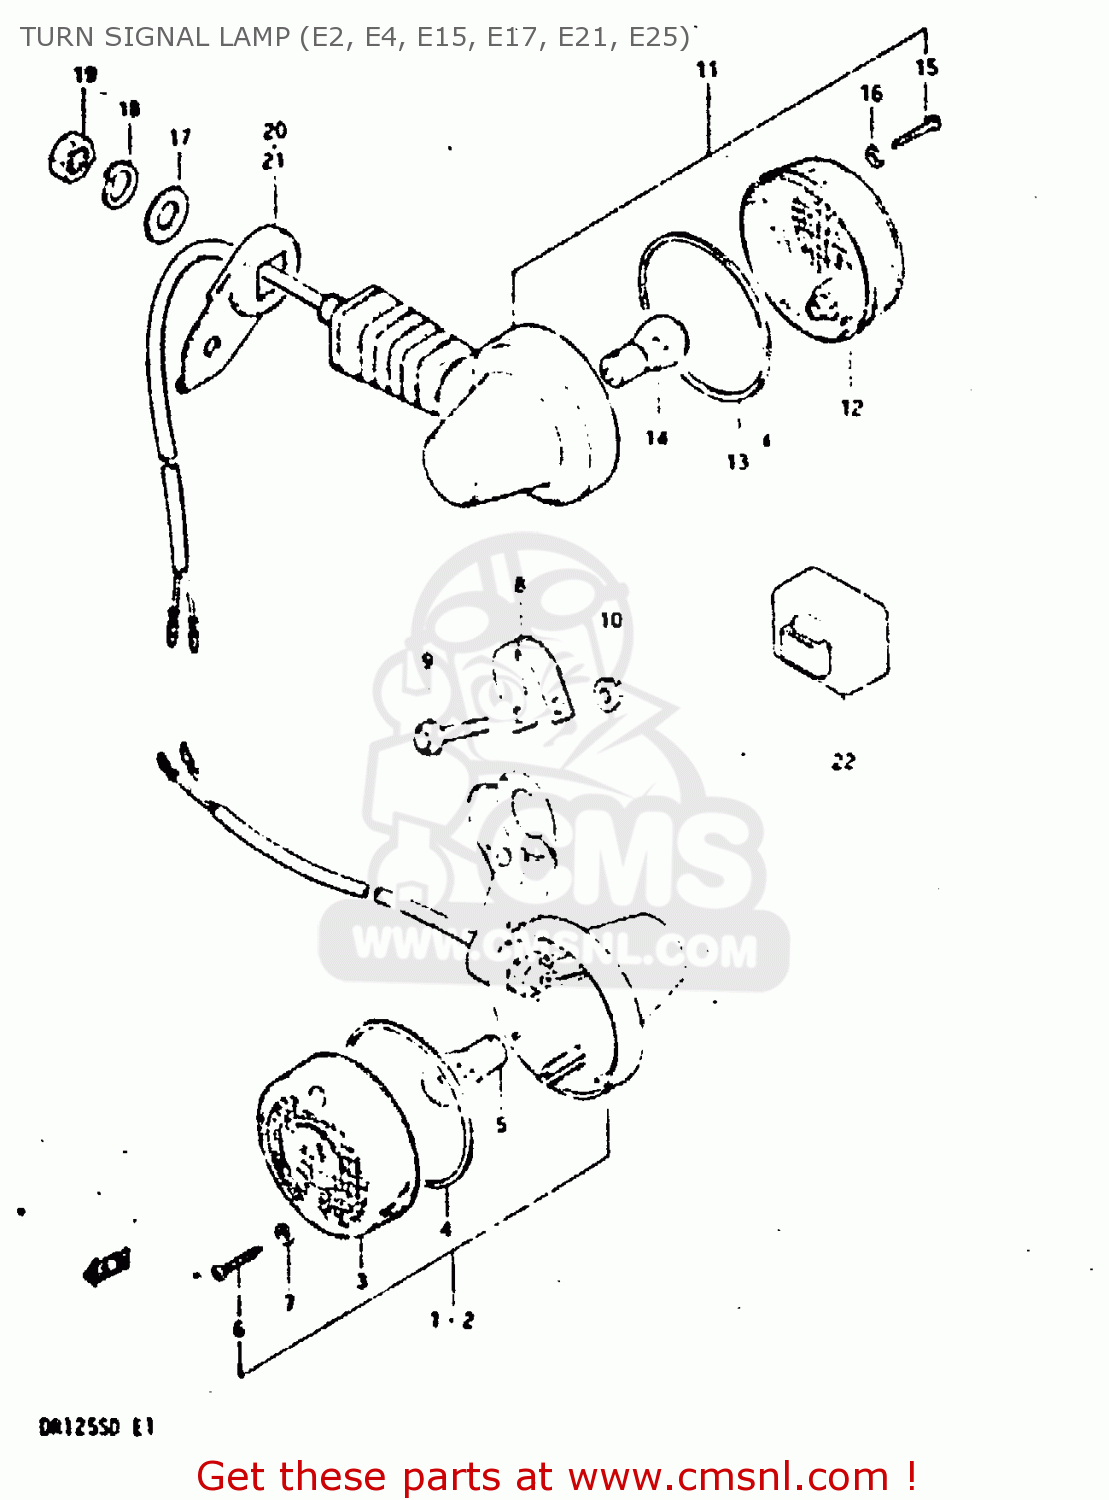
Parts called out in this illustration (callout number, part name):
1	LAMP, FRONT TURN SIGNAL RH
2	LAMP, FRONT TURN SIGNAL LH
3	LENS
4	GASKET (NAS)
5	BULB 12V 21W
6	SCREW TAPP.
7	GASKET (NAS)
8	PLATE
9	BOLT
10	NUT
11	LAMP ASSEMBLY,REAR TURN SIGNAL
12	LENS
13	GASKET (NAS)
14	BULB 12V 21W
15	SCREW TAPP.
16	GASKET (NAS)
17	WASHER
18	WASHER,LOCK 12
19	NUT
20	BRACKET,REAR TURN SIGNAL
21	BRACKET,REAR TURN SIGNAL
22	RELAY,TURN SIGNAL
